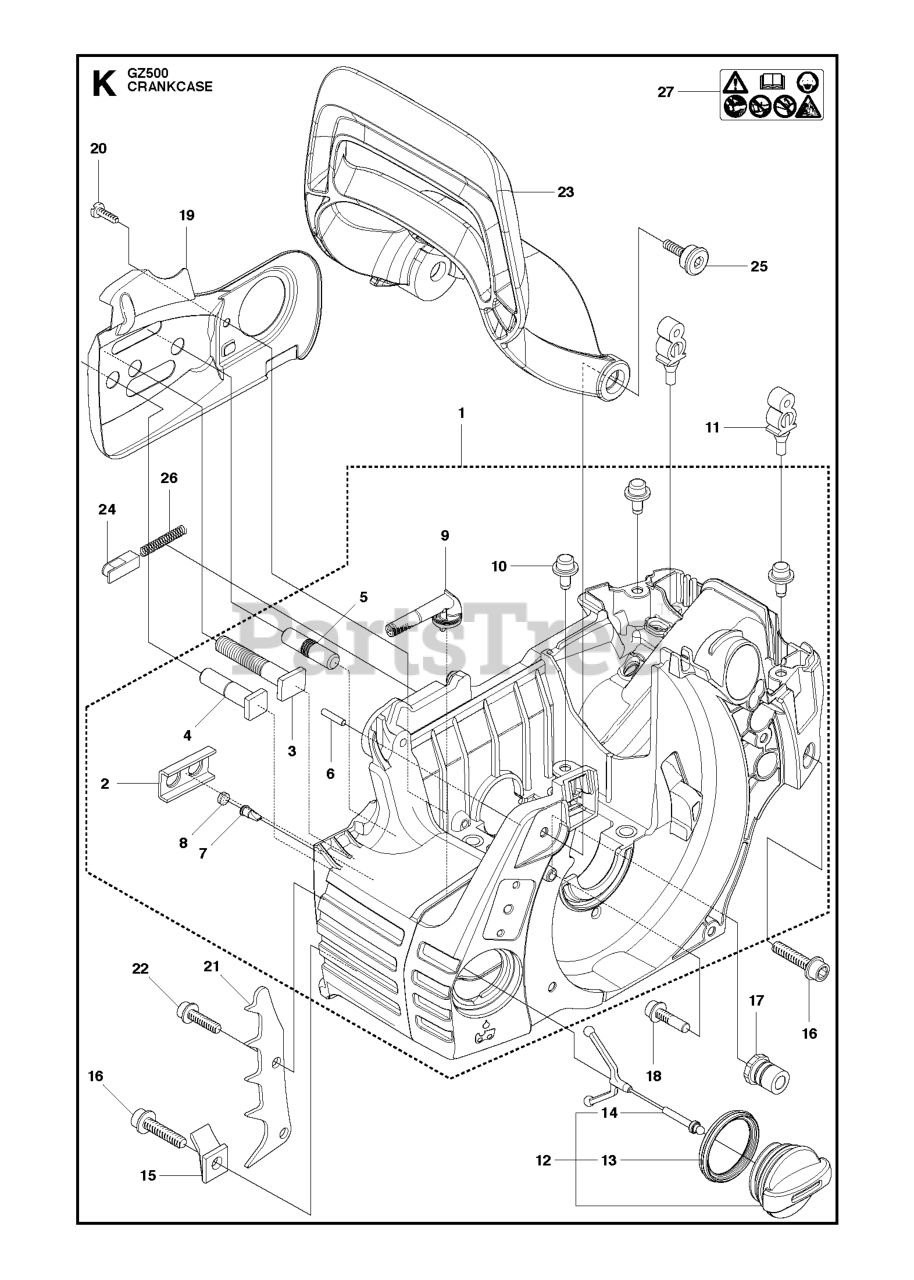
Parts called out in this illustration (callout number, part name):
1	CRANKCASE
2	STIFFENING PLATE
3	BAR BOLT
4	BAR BOLT (X2)
5	BAR BOLT
7	VALVE-CHECK (DUCKBILL)
8	FILTER
9	OIL SCREEN
10	GUIDE PEN
11	CARBURETOR MOUNTING
12	TANK CAP ASSY
14	TANK LOCK
15	CHAIN CATCHER PIN
16	SCREW IHSCFT
17	LATERAL SUPPORT
19	CHAIN GUIDE PLATE
20	SCREW CCRPANT
21	FELLING DOG
23	HAND GUARD
26	POSITION SPRING
